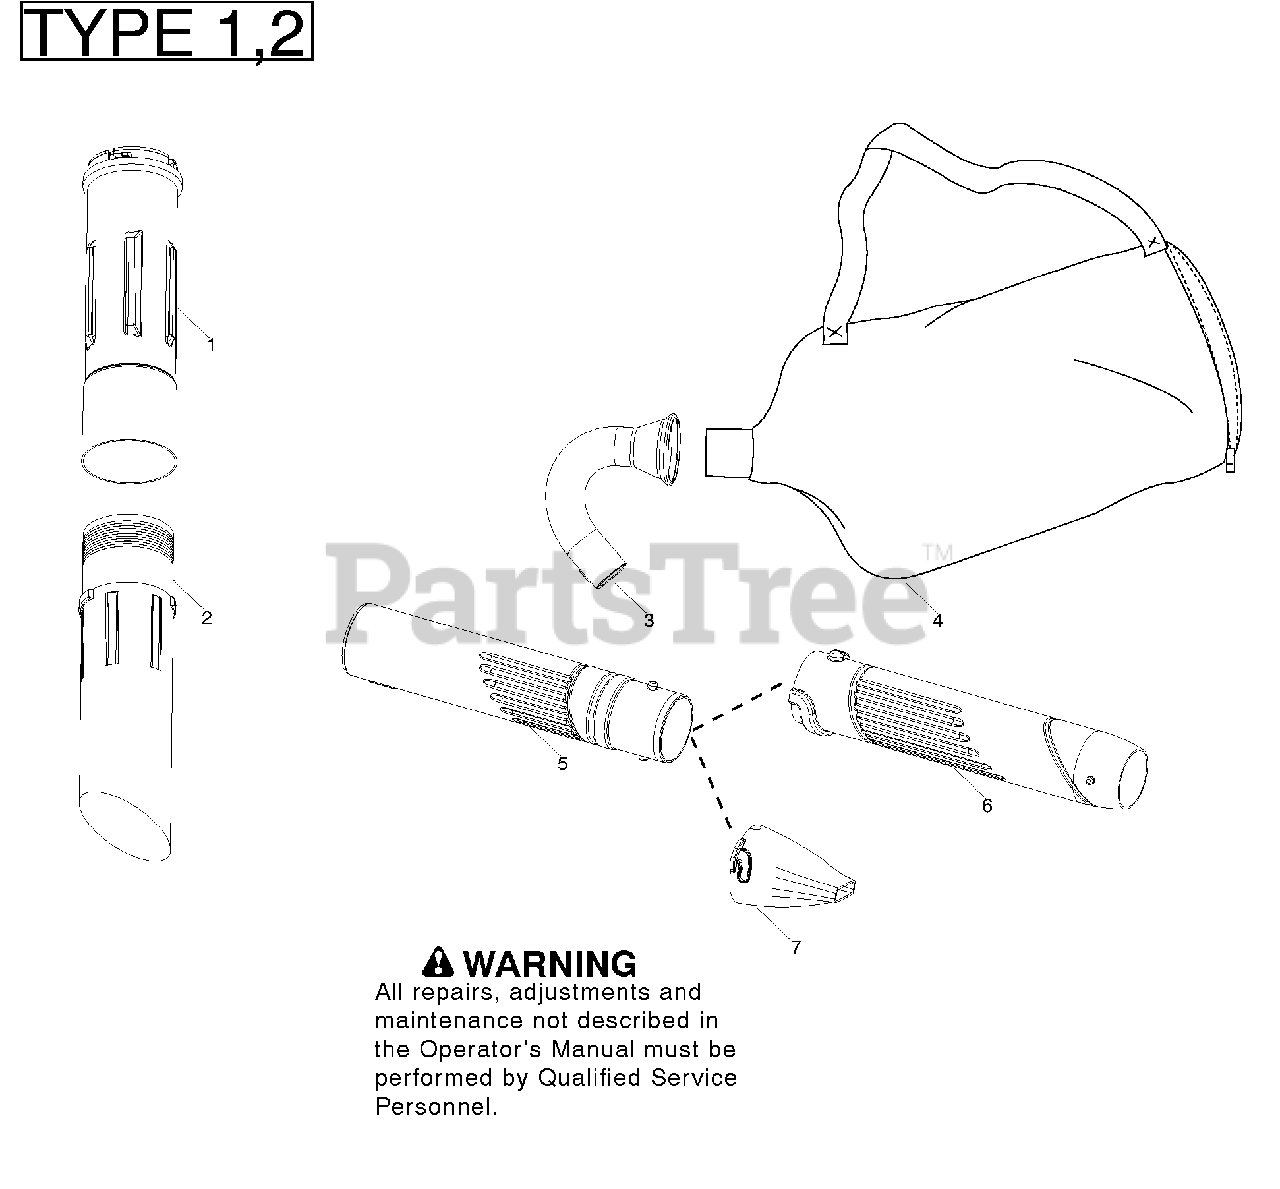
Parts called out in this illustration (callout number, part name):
1	Tube - Upper Vac
2	Tube - Lower Vac
3	Tube - J
4	Assy - Vac Bag
5	Tube - Upper Blower
6	Tube - Lower Blower
7	Nozzle - High Speed
